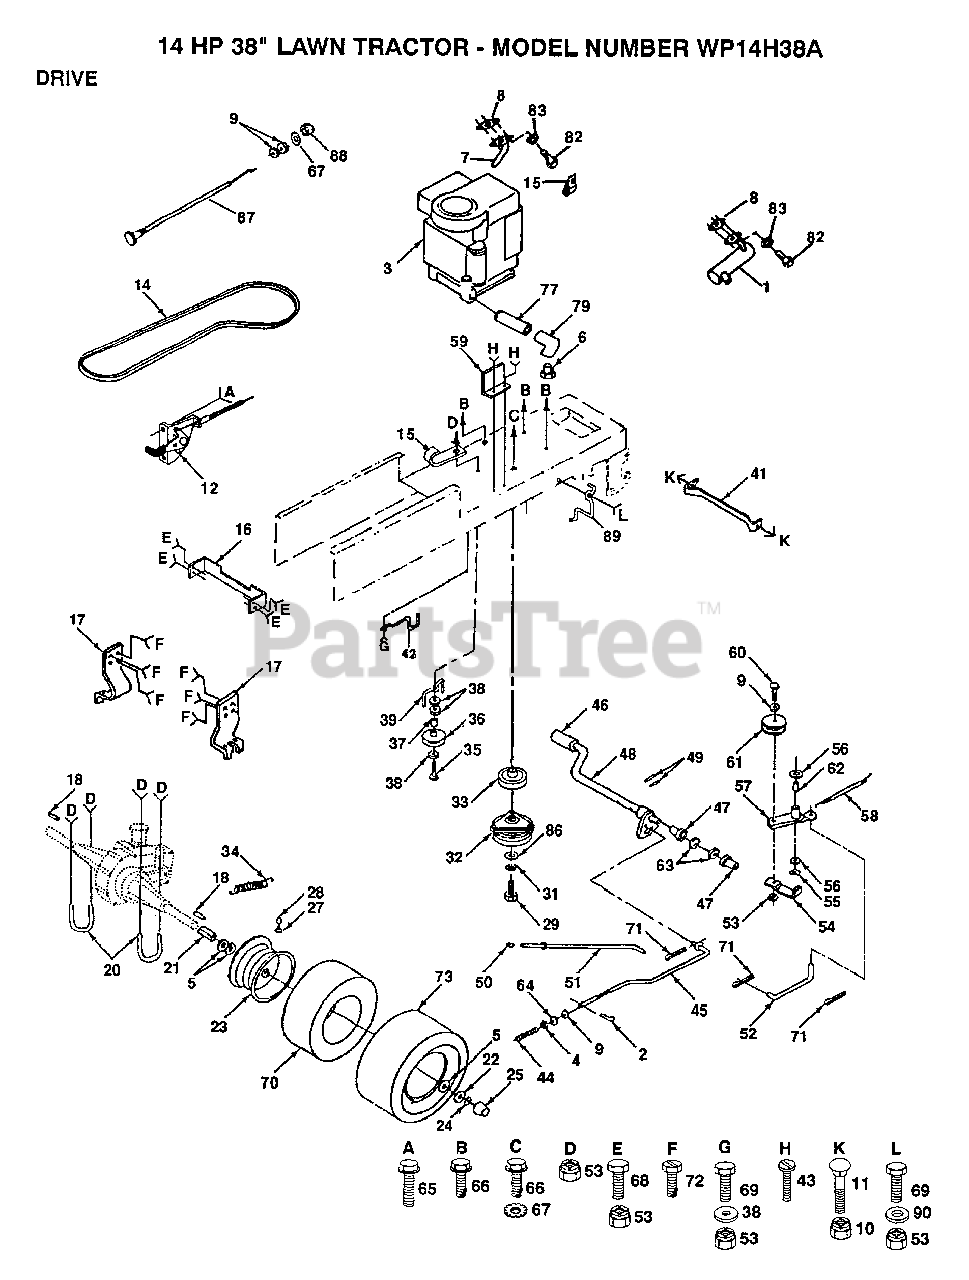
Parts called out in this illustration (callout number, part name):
2	RETAINER M
4	NUT
5	WASHER
7	EXHAUST TUBE T
9	WASHER
11	BOLT
12	THROTTLE CONTROL
15	CLIP T
16	PLATE TRANS SUPT
17	BRKT TRANSAXLE
18	SQUARE KEY
20	U BOLT
21	SPACER SPLIT
22	WASHER
24	E-RING LT
25	HUB CAP
27	VALVE STEM LT
28	VALVE CAP
31	LOCKWASHER
35	BOLT
37	SPACER T
38	WASHER
39	BELT KEEPER LT
42	KEEPER.BELT.ENG.L
43	SCREW
44	SPRING ROD LT
46	PEDAL COVER T
47	NYLON BEARING
50	PLUNGER CAP T
51	BRAKE PARK ROD
52	"LINK, CLUTCH T"
54	RETAIN BELT
55	KLIP RING
56	WASHER LT
57	ARM IDLER
58	"SPRING, RETURN LT"
59	BRACKET LT
62	"LY, BEARING"
63	WASHER LT
64	NUT
65	SCREW LT
66	SCREW LT
67	LOCKWASHER
69	BOLT
70	TUBE.18X9.5-8
71	COTTER PIN
72	SCREW
77	PIPE NIPPLE LT
79	ELBOW
83	LOCKWASHER
86	WASHER
87	CHOKE CONTROL
89	KEEPER BELT ENG
90	WASHER
